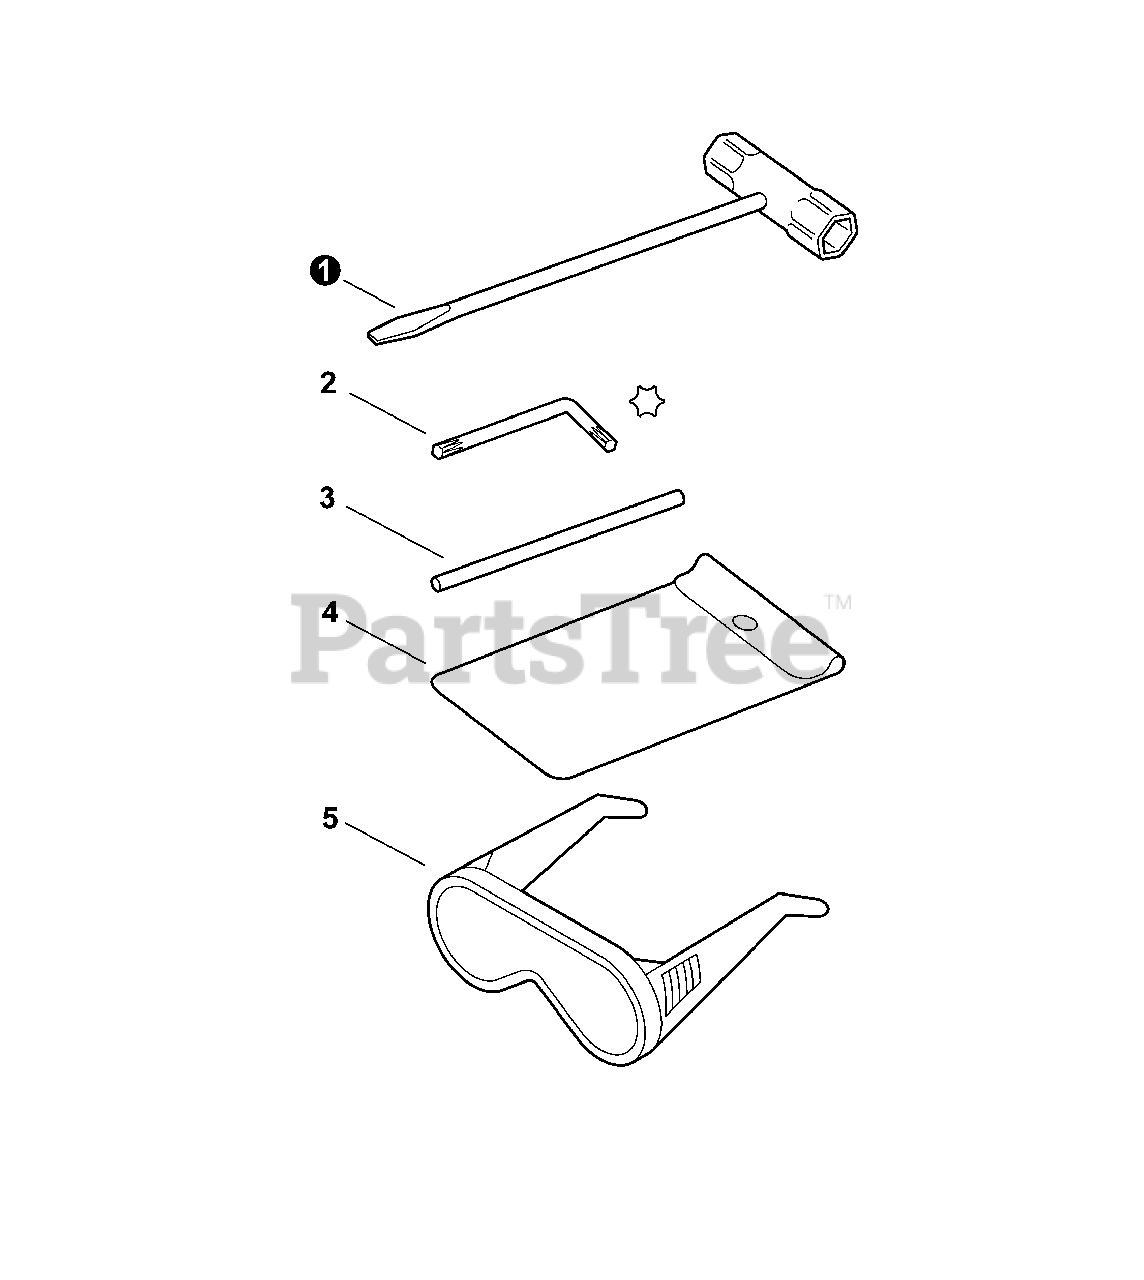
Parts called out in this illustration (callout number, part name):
1	T-WRENCH - 17×19mm
2	KEY - TORX -- T27
3	ROD, LOCKING - 5×120mm
4	BAG,TOOL
5	GOGGLES
